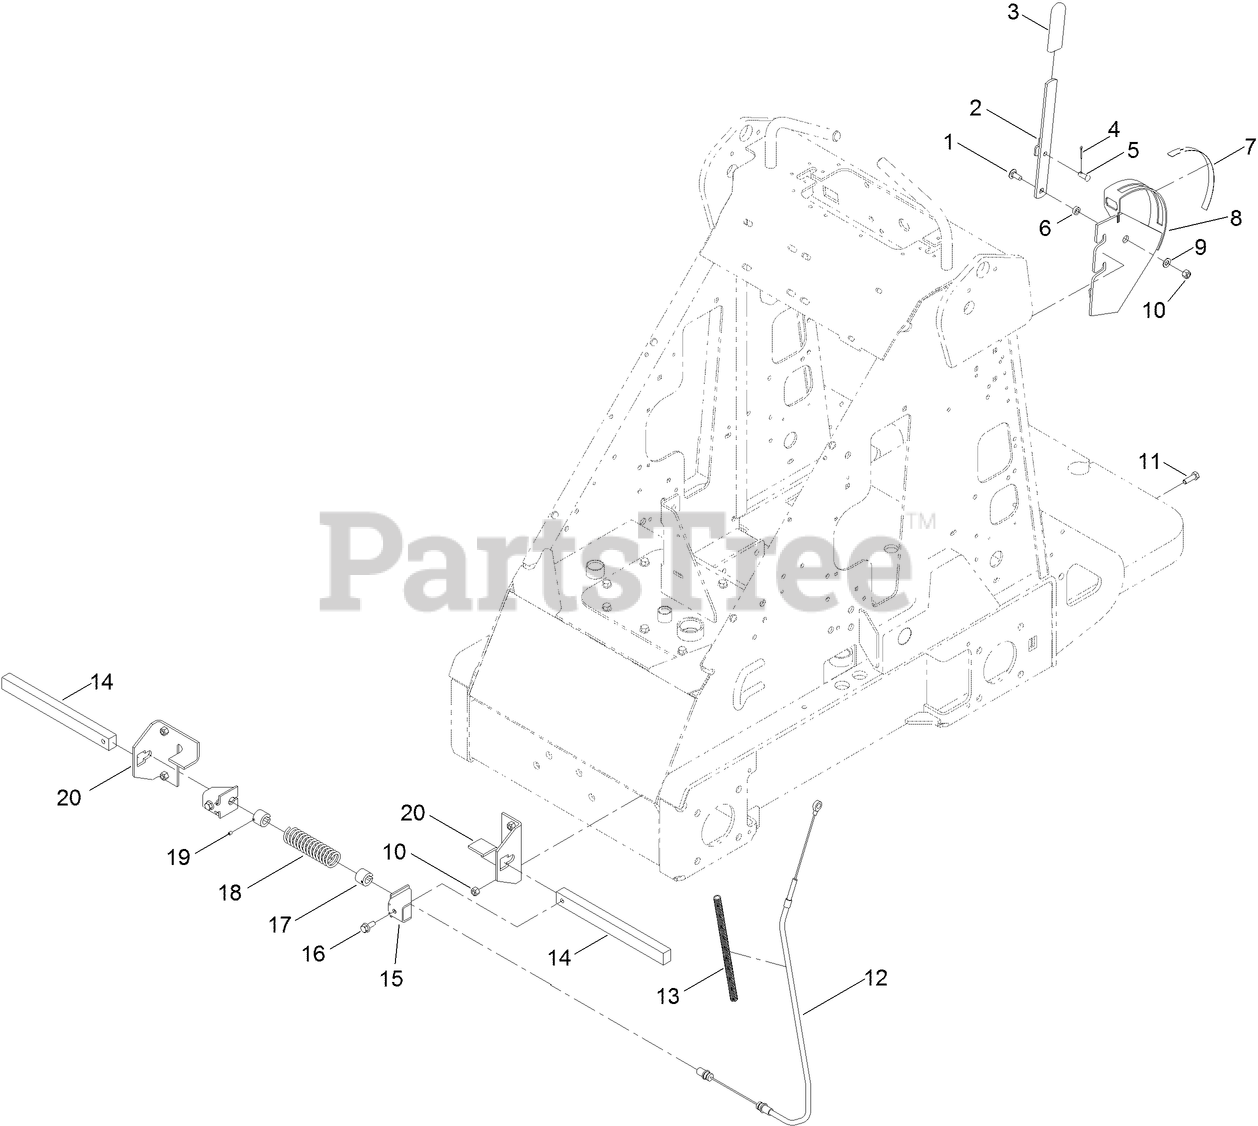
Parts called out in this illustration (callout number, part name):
1	SCREW-CARR
2	LEVER-BRAKE
3	GRIP-HANDLE
4	PIN-COTTER
5	PIN-CLEVIS
6	HUB-LEVER
7	DECAL-PARKING BRAKE
8	PLATE-BRAKE
9	WASHER-PLAIN
10	NUT-LOCK, NI
11	SCREW-HH
13	TUBE-CONVOLUTED
14	BAR-BRAKE
15	BRACKET-CABLE
16	SCREW-HHF
17	TUBE-GUIDE
19	SCREW-HSH
20	BRACKET-BRAKE
